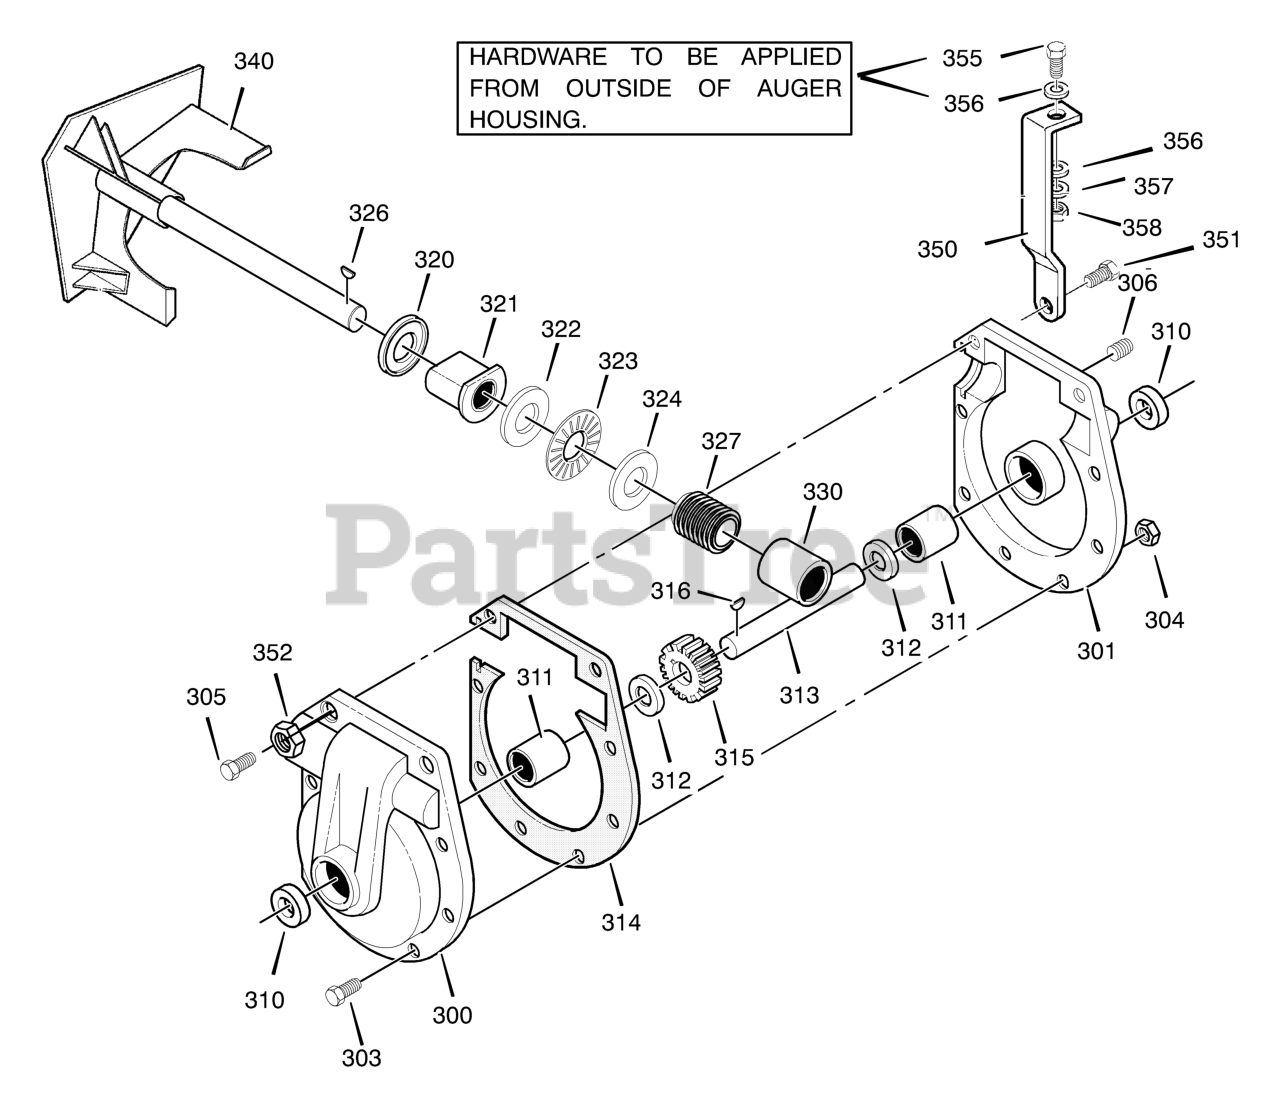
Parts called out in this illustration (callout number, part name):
300	CASE, GEAR, RH
301	CASE, GEAR, LH
303	SCREW, 5/16-24 x 1.00
304	NUT, 5/16-24
305	SCREW, 5/16-24 x 1.75
306	PLUG, PIPE 0.25-18
310	SEAL, OIL
311	BEARING, SLEEVE
312	WASHER, FLAT
313	SHAFT, AUGER OUTPUT
314	GASKET, GEAR BOX
315	WORM GEAR
316	KEY, WOODRUFF #91
320	RING, QUAD 0.924 ID
321	BEARING, FLANGE
322	WASHER, FLAT
323	BEARING, ROLLER
324	WASHER, FLAT
330	BEARING, SLEEVE
340	IMPELLER
